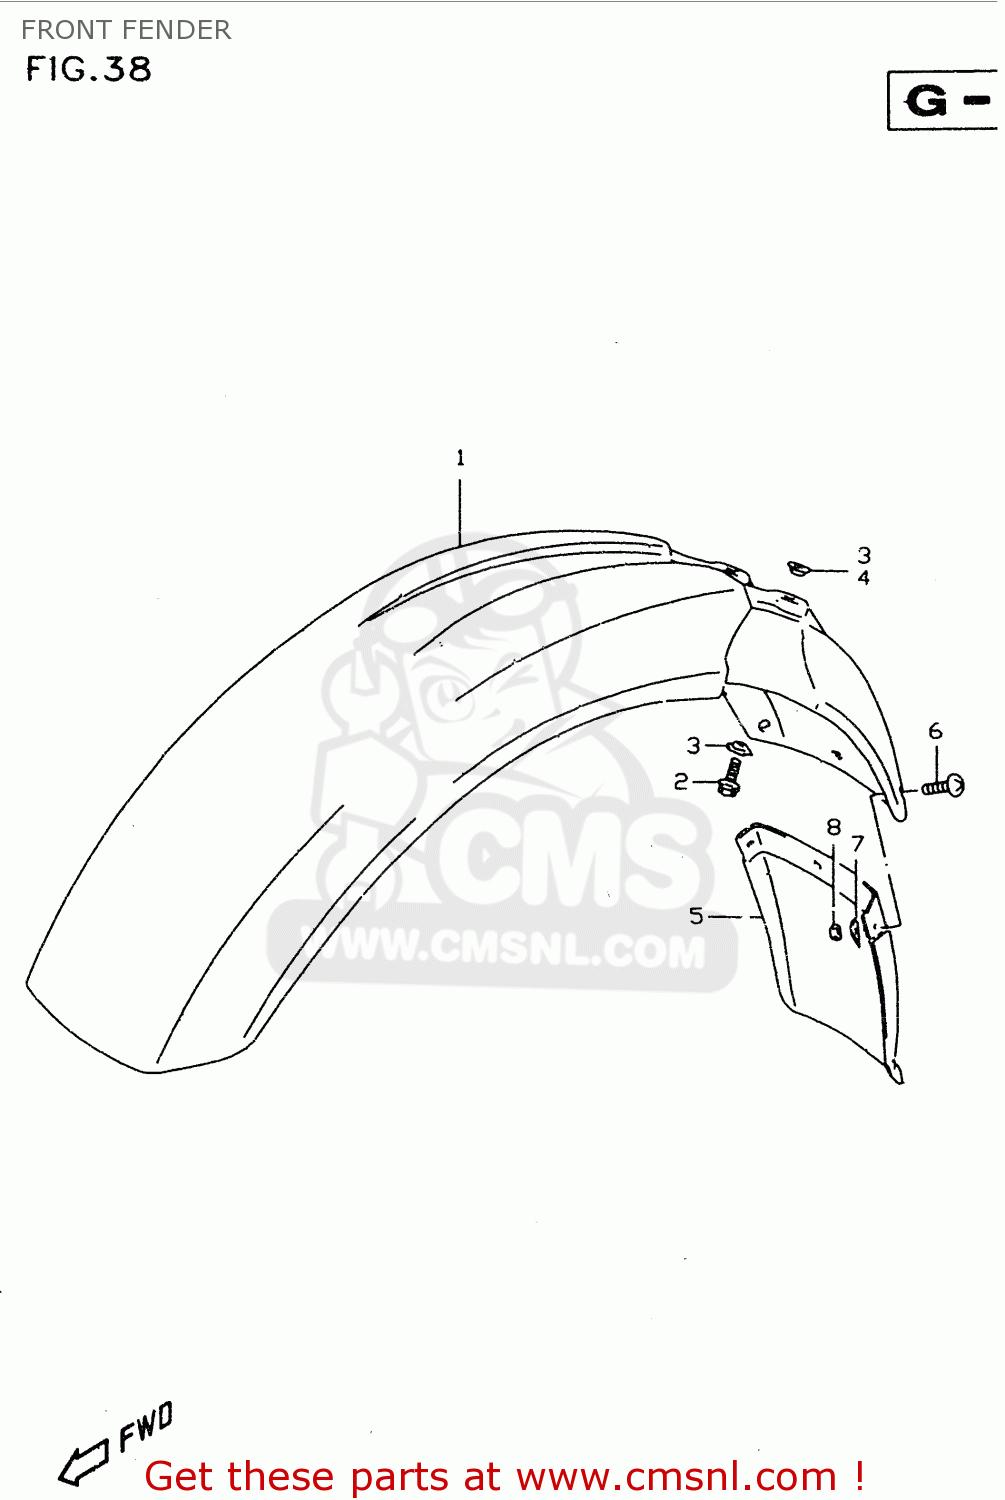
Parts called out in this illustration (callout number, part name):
1	FENDER,FR
2	BOLT
3	WASHER
4	WASHER
5	MUD GUARD, FRONT FENDER
6	SCREW
7	WASHER(5.5X16X1.2)
8	NUT
